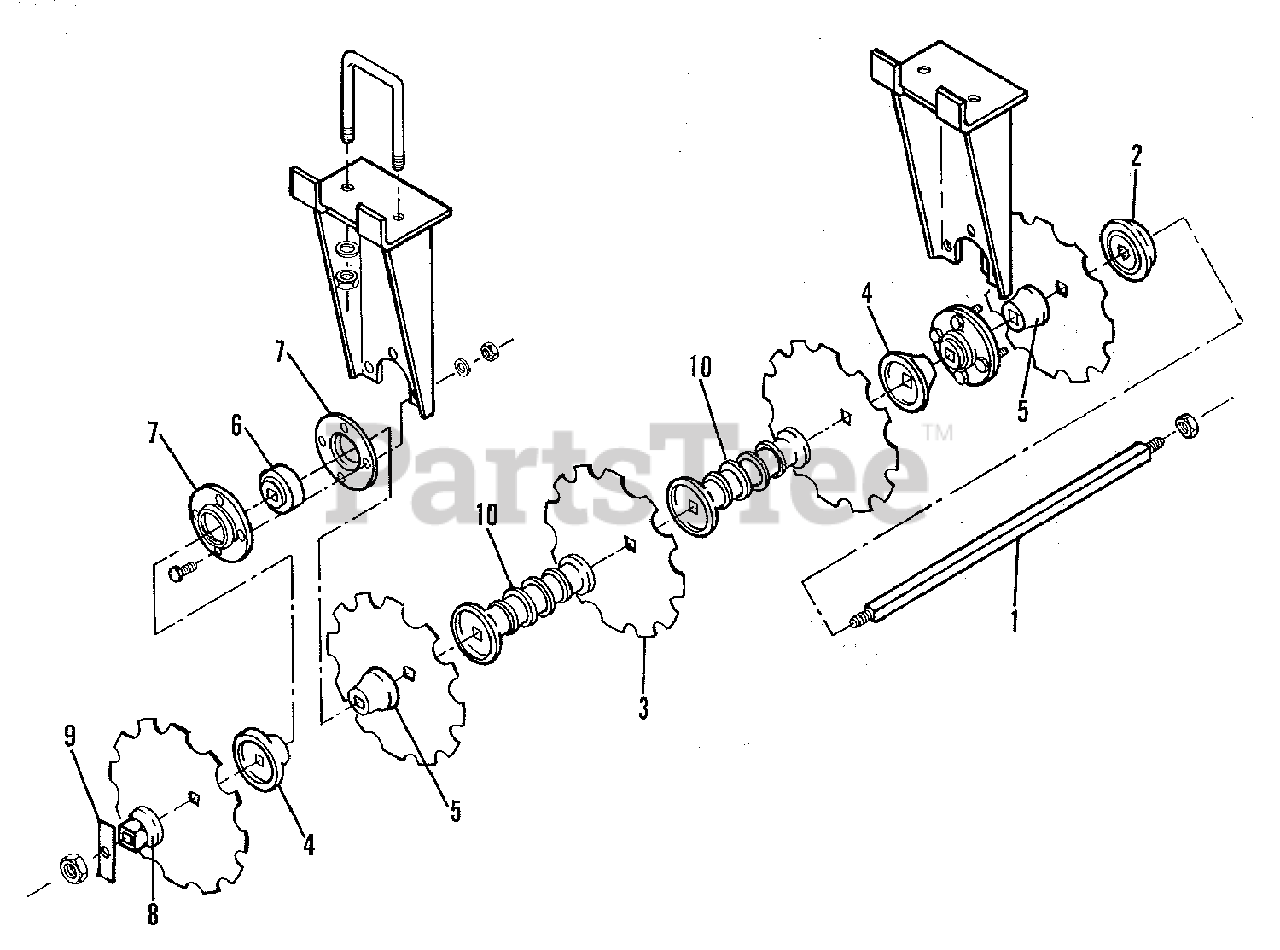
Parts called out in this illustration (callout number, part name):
1	AXLE, Gang, 33-1/2" Long (For 5 Blades)
1	AXLE, Gang, 26" Long (For 4 Blades)
2	WASHER, Bumper
3	BLADE, Notched (18" Diameter)
3	BLADE, Notched (20" Diameter)
4	SPOOL, Bearing, Outer
5	SPOOL, Bearing, Inner
7	FLANGE, Bearing
7	BOLT, Carriage, 1/2NC x 1-1/4
7	LOCKWASHER, 1/2
8	WASHER, End
9	PLATE, Lock
10	SPOOL, Spacing
